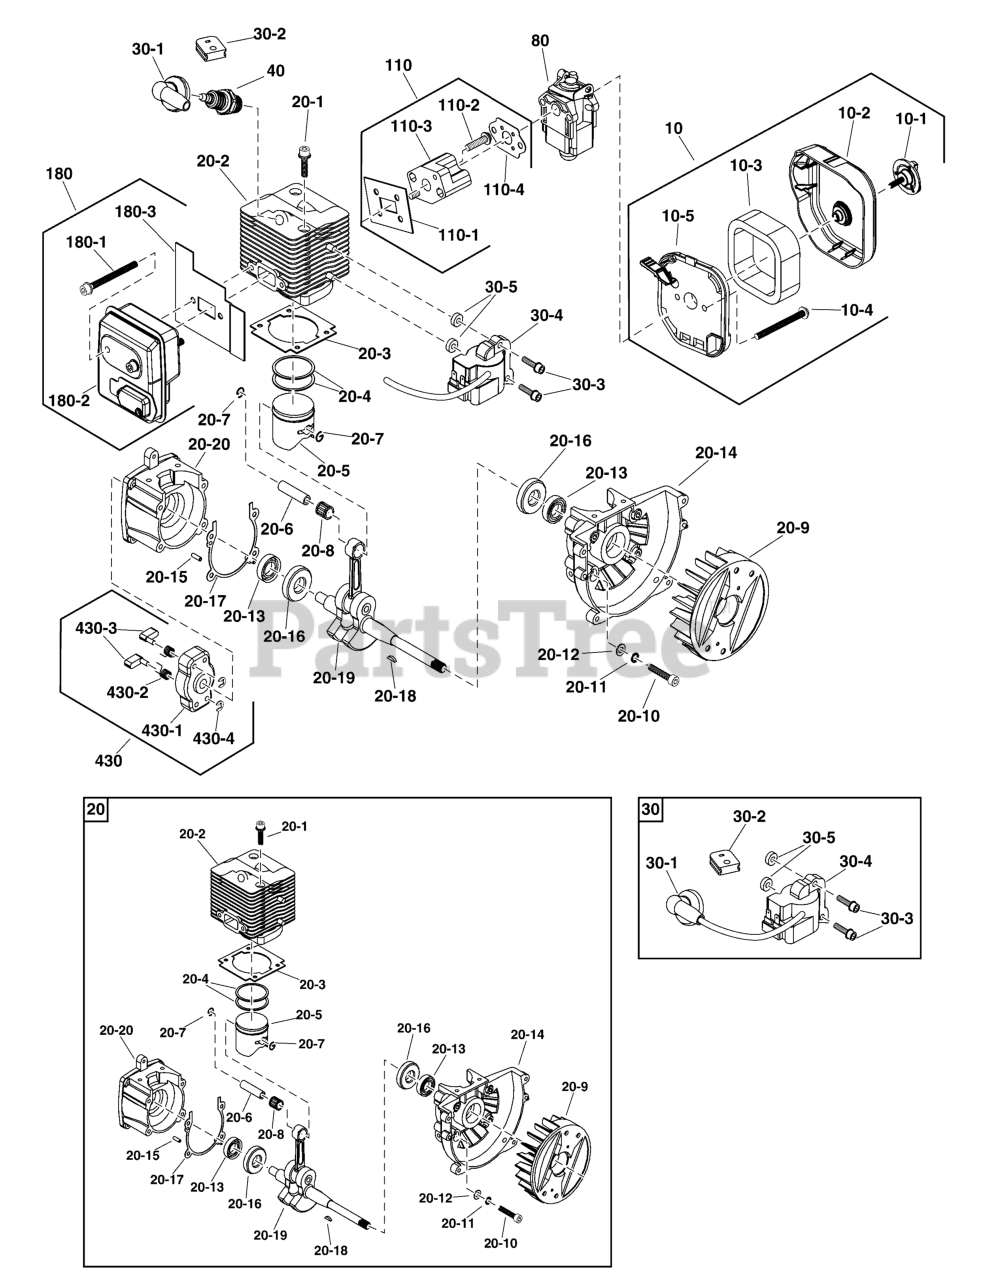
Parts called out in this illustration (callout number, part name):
10	COVER ASSEMBLY, Carburetor
10-2	COVER, Air Filter
10-3	AIR CLEANER ELEMENT
10-5	INSIDE COVER ASSEMBLY, Air Cleaner
20-2	CYLINDER HEAD
20-3	GASKET, Cylinder Head
20-4	PISTON Ring
20-5	PISTON
20-6	PIN, Piston
20-7	CIRCLIP, Piston
20-8	NEEDLE BEARING
20-9	FLYWHEEL
20-13	OIL SEAL
20-14	CRANKCASE, Front
20-15	ORIENTATION PIN
20-16	BALL BEARING
20-17	GASKET, Crankcase
20-18	KEY, Crankshaft
20-19	CRANKSHAFT ASSEMBLY
20-20	CRANKCASE, Rear
30	IGNITION UNIT
30-1	BOOT, Spark Plug
30-2	PLUG
30-4	MAGNETO STARTER
30-5	PAD, Insulation
40	SPARK PLUG, NGK BPMR7A
80	CARBURETOR
110	INTAKE MANIFOLD ASSEMBLY
110-1	GASKET, Cylinder
110-3	INLET MANIFOLD
110-4	GASKET, Carburetor
180	MUFFLER ASSEMBLY
180-2	MUFFLER
180-3	GASKET, Muffler
430	STARTER PULLEY ASSEMBLY
430-1	BODY, Starter Pulley
430-2	SPRING, Starter Pulley
430-3	ARM, Starter Pulley
430-4	E-CLIP
